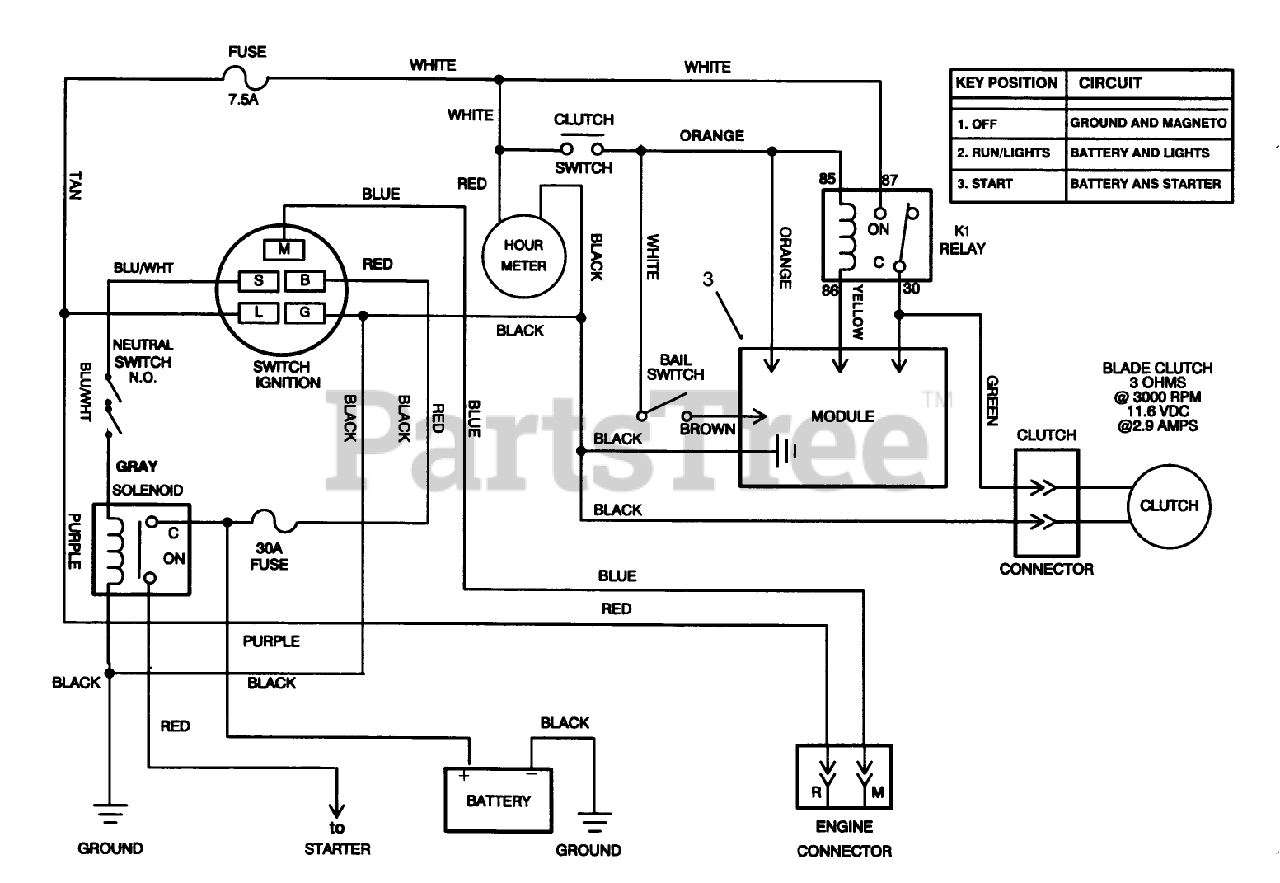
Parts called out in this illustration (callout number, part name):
1	WIRE HARNESS-14HP HYDRO
2	RELAY
3	Module
